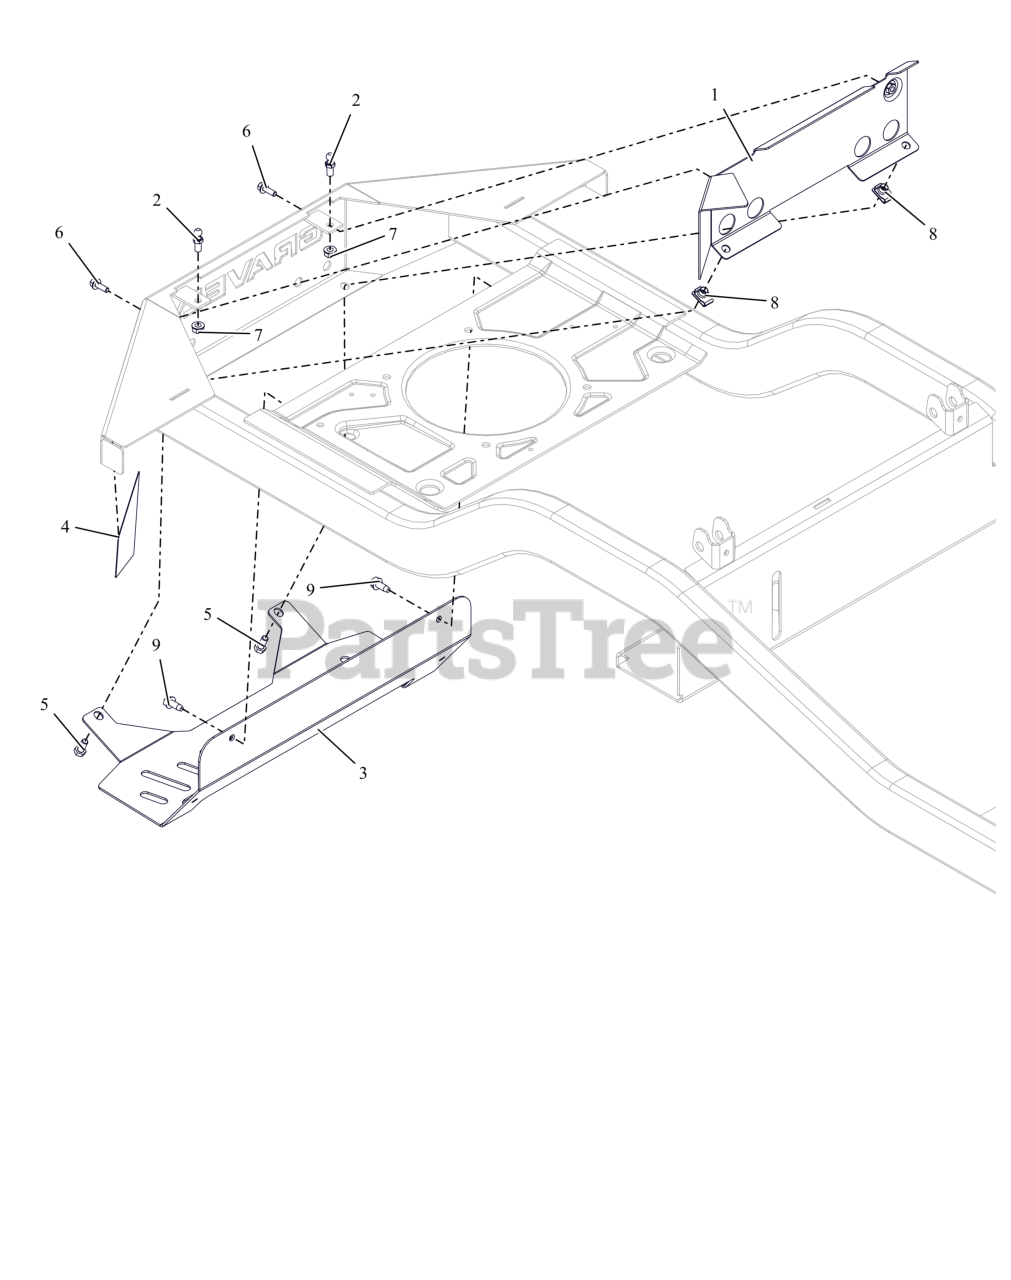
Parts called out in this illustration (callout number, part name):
1	WMT, HEAT BAFFLE
2	STUD- BALL
3	SHIELD, HEAT (HD)
4	TAPE, HEAT DEFLECTOR
5	BLT,HEX .31-18X.75 G5 ZCC
6	BLT,HEX-FLG .25-20X.75 G5 BFP
7	NUT,LK-CTR-FLG .31-18 GF ZCC
8	NUT-CLIP RETAINER 5/16-18X.56
9	SCR,TAP .312-18X.75 HWH TR ZCC
